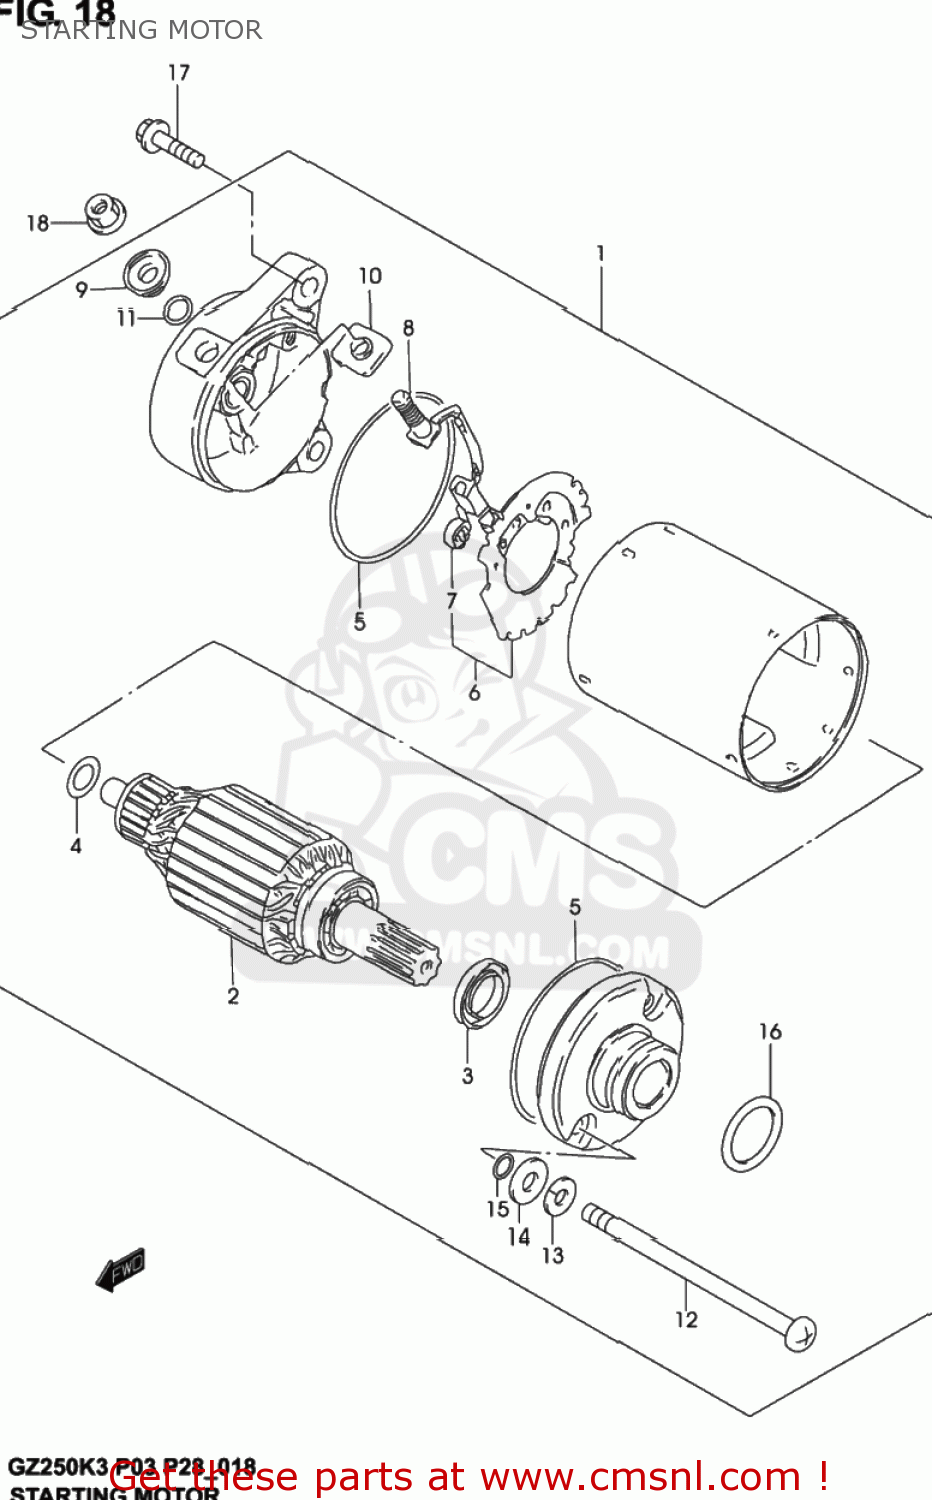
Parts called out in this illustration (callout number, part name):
1	MOTOR ASSY,STARTING
2	ARMATURE
3	SEAL,OIL
4	SHIM SET,STARTING MOTOR
5	O RING
6	HOLDER,BRUSH
7	SPRING
8	BRUSH SUB ASSY,STARTING MOTOR
9	BUSHING
10	BUSH,B
11	O RING
12	BOLT
13	WASHER,LOCK
14	WASHER
15	O RING
16	O RING(D:3,ID:24.5)
17	SCREW
18	NUT
